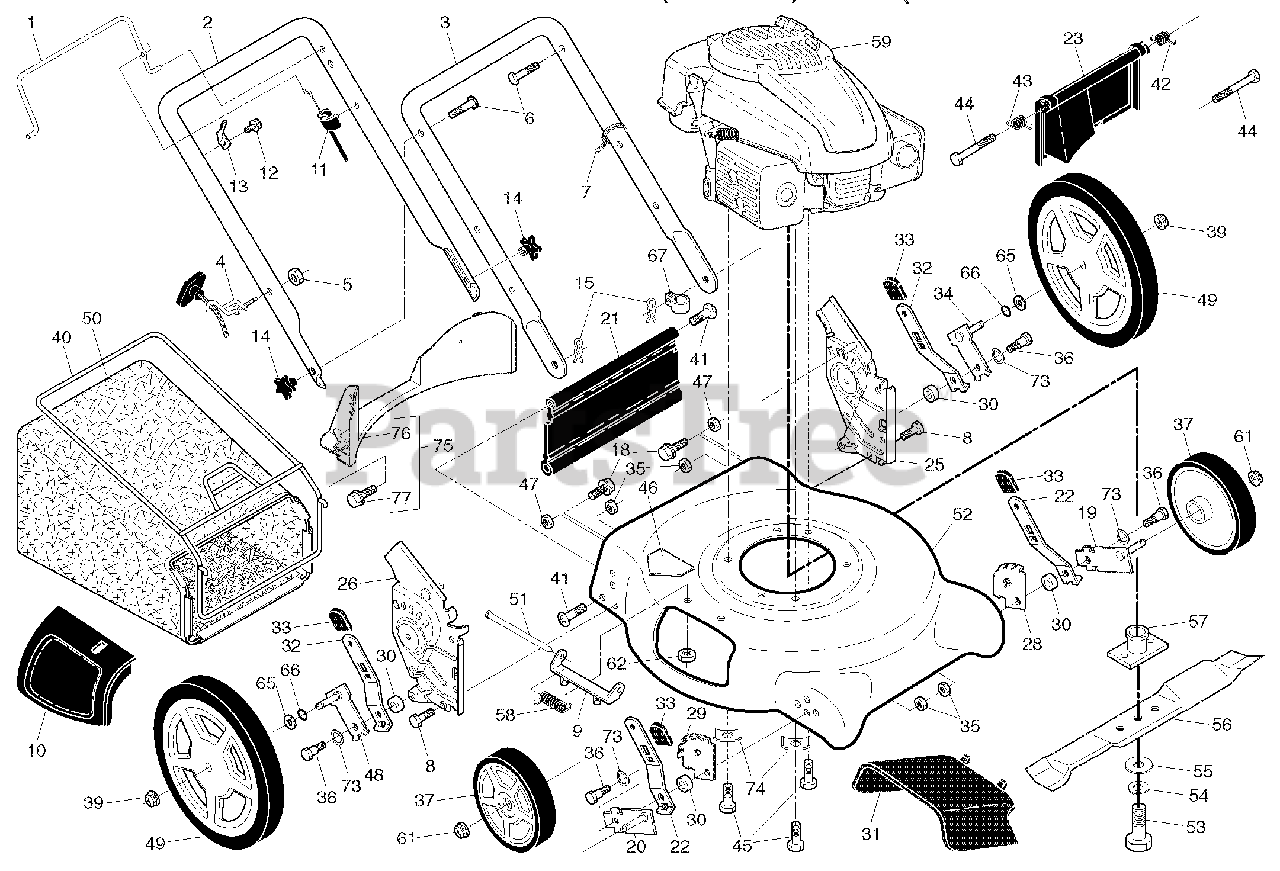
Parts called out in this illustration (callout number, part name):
1	Control Bar
2	Upper Handle
3	Lower Handle
4	Rope Guide
5	Nut, Hex
6	Handle Bolt
7	Wire Tie
8	Bolt, Hex Head 5/16-18 x 3/4
9	Hinge Bracket
10	Mulcher Door
11	Engine Zone Control Cable
12	Hex Washer Head Screw
13	UP-STOP BRACKET
14	Handle Knob
15	Hairpin Cotter
18	SCREW.HEX.WASHEAD.1/4-20 X 3/8
19	Axle Arm Assembly, Front, LH
20	Axle Arm Assembly, Front, RH
21	Kit, Rear Skirt
22	Selector Spring, Front
23	Rear Door Assembly
25	Handle Bracket Assembly, LH
26	Handle Bracket Assembly, RH
28	Wheel Adjusting Bracket, LH
29	Wheel Adjusting Bracket, RH
31	Discharge Deflector
32	Selector Spring, Rear
33	Selector Knob
34	Axle Arm Assembly, Rear, LH
35	Locknut, Hex 5/16-18
36	Shoulder Bolt
37	Wheel & Tire Assembly, Front
39	Flanged Locknut, Hex
40	Frame, Grassbag
41	Hinge Screw
42	Spring, Rear Door, LH
43	Spring, Rear Door, RH
44	Bolt, Rear Door
45	Screw, Hex Head, Threaded, Rol
46	Danger Decal
47	Nut, Hex
48	Axle Arm Assembly, Rear, RH
49	Wheel & Tire Assembly, Rear
50	Grassbag
51	Hinge Rod
52	Kit, Lawn Mower Housing (Inclu
53	Screw, Hex Head, Grade 8 3/8-2
54	Helical Lockwasher
55	Hardened Washer
56	21" Blade
57	Blade Adapter
58	Hinge Spring
59	Engine, Kohler, Model Number XT149-0217-EA (For engine service and replacement parts,
61	Nut, Hex
62	Locknut, Hex 1/4-20
65	Washer, Flat
67	Clip, Cable
73	Washer, Curved, Cylindrical
74	Washer, Special, Engine
75	Kit, Rear Baffle (Includes 3 S
76	Baffle, Rear
77	Screw, Rear Baffle
